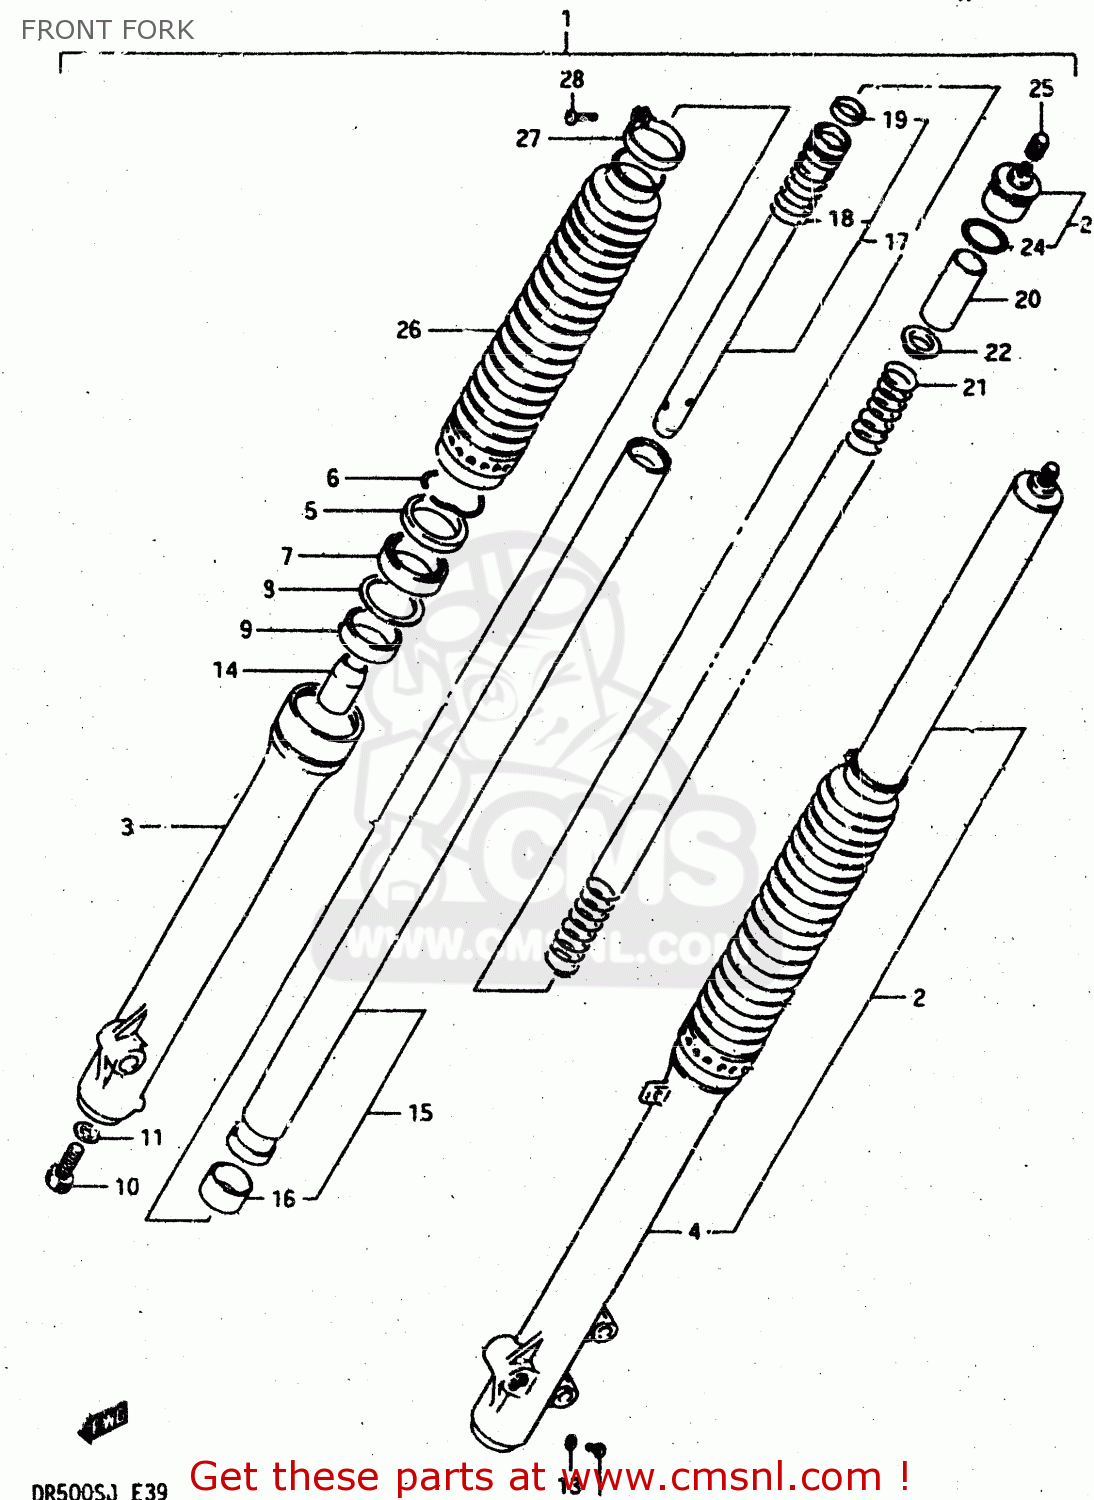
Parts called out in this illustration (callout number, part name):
1	DAMPER ASSEMBLY,FRONT FORK,RIGHT
2	DAMPER ASSEMBLY,FRONT FORK,LEFT
3	TUBE,FORK,OUTER,RIGHT
4	TUBE,FORK,LEFT,OUTER
5	SEAL,DUST
6	RING,OIL SEAL STOPPER
7	SEAL,OIL
8	WASHER,FORK OIL SEAL
9	METAL,FR FORK SLIDE
10	BOLT,CYLINDER
11	GASKET,CYLINDER (NAS)
12	SCREW 4X6
13	GASKET,DRAIN,PLUG (NAS)
14	PIECE,FRONT FORK OIL LOCK
15	TUBE,FORK,INNER
16	METAL,SLIDE FR FORK
17	CYLINDER,FRONT FORK
18	SPRING,REBOUND
19	RING,FRONT FORK PISTON
20	SPACER,FRONT FORK SPRING
21	SPRING,FRONT FORK
22	GUIDE,FR FORK SPRING
23	CAP,FORK INNER TUBE
24	O RING
25	CAP
26	BOOT
27	BAND,BOOT
28	SCREW 4X10
